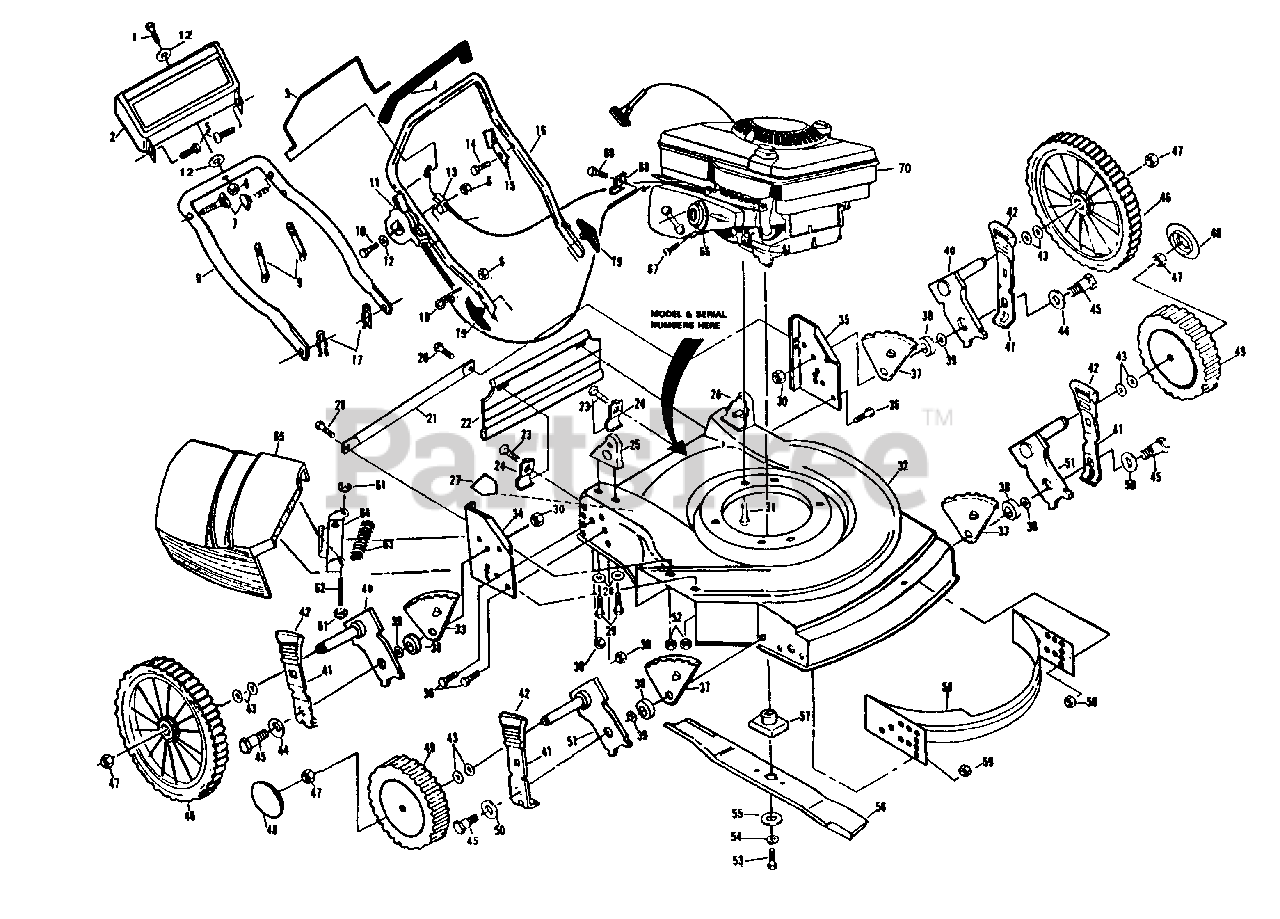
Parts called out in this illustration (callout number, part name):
1	Hex Head Washer Screw 1/4-20 x 1-1/2
2	Trim Plate
3	Control Bar
4	Handle Grip
5	Self-tapping Screw #10-24 x 5/8
6	Locknut 1/4-20
7	Handle Bolt 5/16-18 x 1-3/4
8	Lower Handle
9	Wire Tie
10	Machine Screw 1/4-20 x 2-1/8
11	Throttle Control
13	Engine Zone Control Cable
14	Hex Washer Head Screw #10-24 x 1/2
15	Up-Stop Bracket
16	Upper Handle
17	Hairpin Cotter
18	Rope Guide
19	Handle Knob
20	Self-tapping Screw 1/4-20 x 1/2
21	Support Rod
22	Rear Skirt
23	Hex Head Washer Screw #10-24 x 1/2
24	Skirt Bracket
25	Handle Bracket Assembly (Right)
26	Handle Bracket Assembly (Left)
27	Danger Decal
29	Thread Cutting Screw 5/16-18 x 1-3/4
30	Locknut 3/8-16
31	Thread Rolling Screw 3/8-16 x 1
32	Lawn Mower Housing
33	Wheel Adjusting Bracket (LF/RR)
34	Wheel Support Bracket (Right)
35	Wheel Support Bracket (Left)
36	Hex Head Bolt 3/8-16 x 3/4
37	Wheel Adjusting Bracket (RF/LR)
38	Spacer
40	Axle Arm Assembly (Rear)
41	Selector Spring
42	Selector Knob
43	Washer
44	Washer
45	Shoulder Bolt 3/8-16
46	Wheel & Tire Assembly 14.0 x 2.0
47	Locknut
49	Wheel & Tire Assembly 8.0 x 2.0
51	Axle Arm Assembly (Front)
52	Locknut
53	Hex Head Screw 3/8-24 x 1-3/8 Gr. 8
54	Helical Washer 3/8
55	Hardened Washer
56	22" Blade
57	Blade Adapter
58	Front Baffle
59	Locknut 3/8-16
61	E-Ring
63	Torsion Spring
64	Housing Bracket Assembly
65	Discharge Guard
66	Muffler Deflector
67	Screw #8-32 x 3/8
68	Cable Clamp
69	Thread Rolling Screw #10-32 x 5/8
70	Engine - Briggs & Stratton
